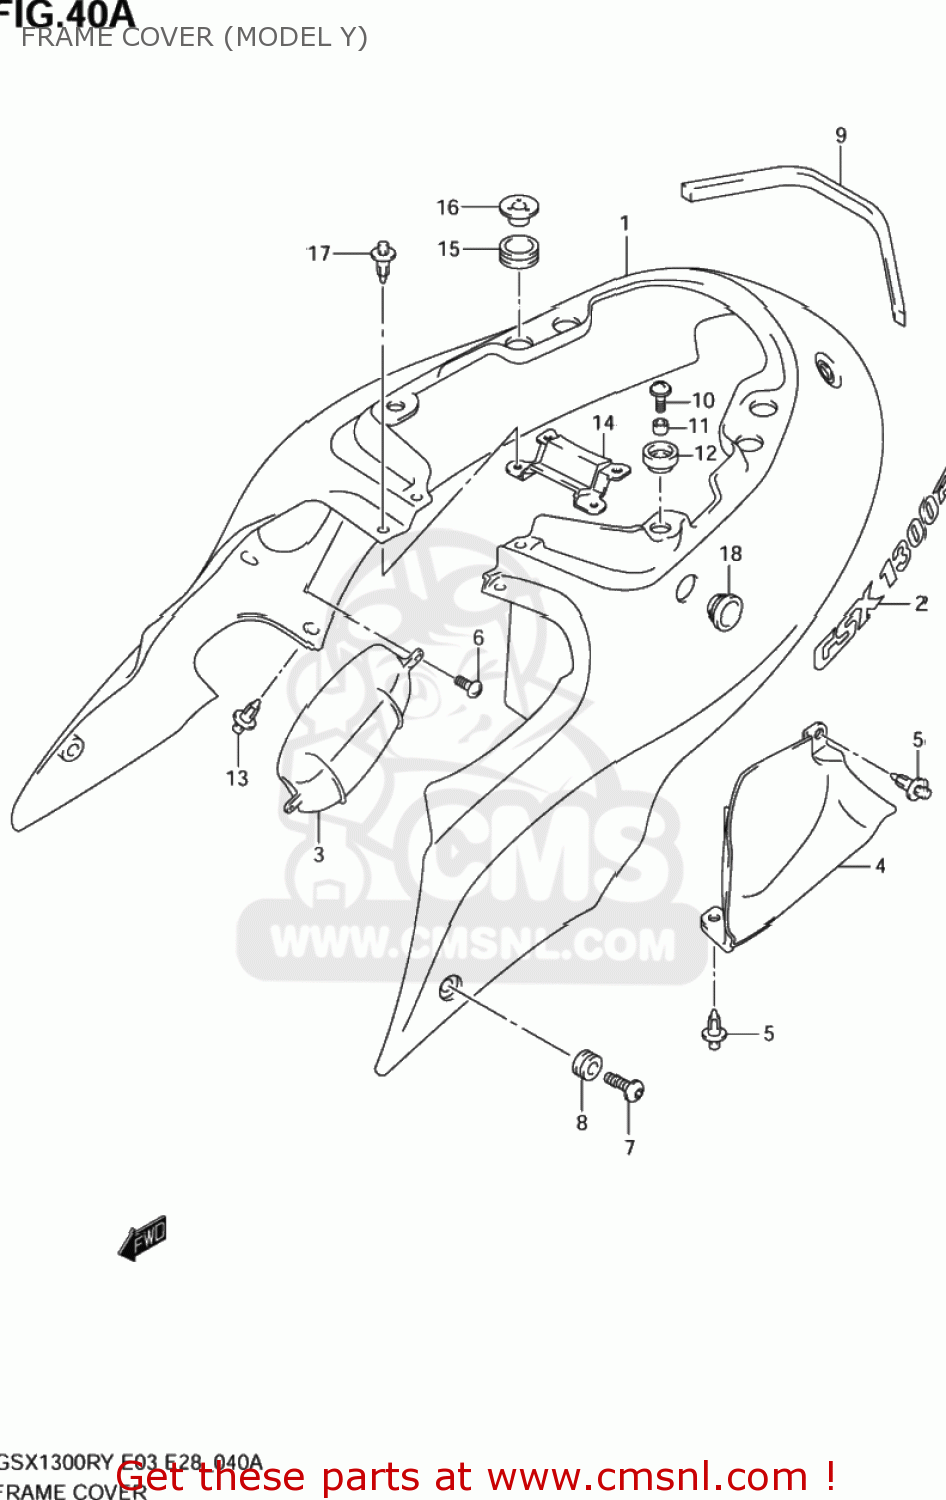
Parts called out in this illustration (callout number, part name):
1	COVER,FRAME(RED)
2	EMBLEM,FRAME COVER
3	CAP,FRAME COVER HOLE,R
4	CAP,FRAME COVER HOLE,L
5	CLIP(BLACK)
6	SCREW
7	SCREW(6X20)
8	CUSHION
9	CUSHION,FRAME COVER UPR
10	SCREW(6X20)
11	SPACER(6.5X10X11)
12	CUSHION
13	CLIP(BLACK)
14	COVER,FRAME CTR
15	CUSHION,FRAME COVER UPR RR
16	WASHER COMP,FRAME COVER
17	CLIP(BLACK)
18	CUSHION,FRAME COVER CTR
